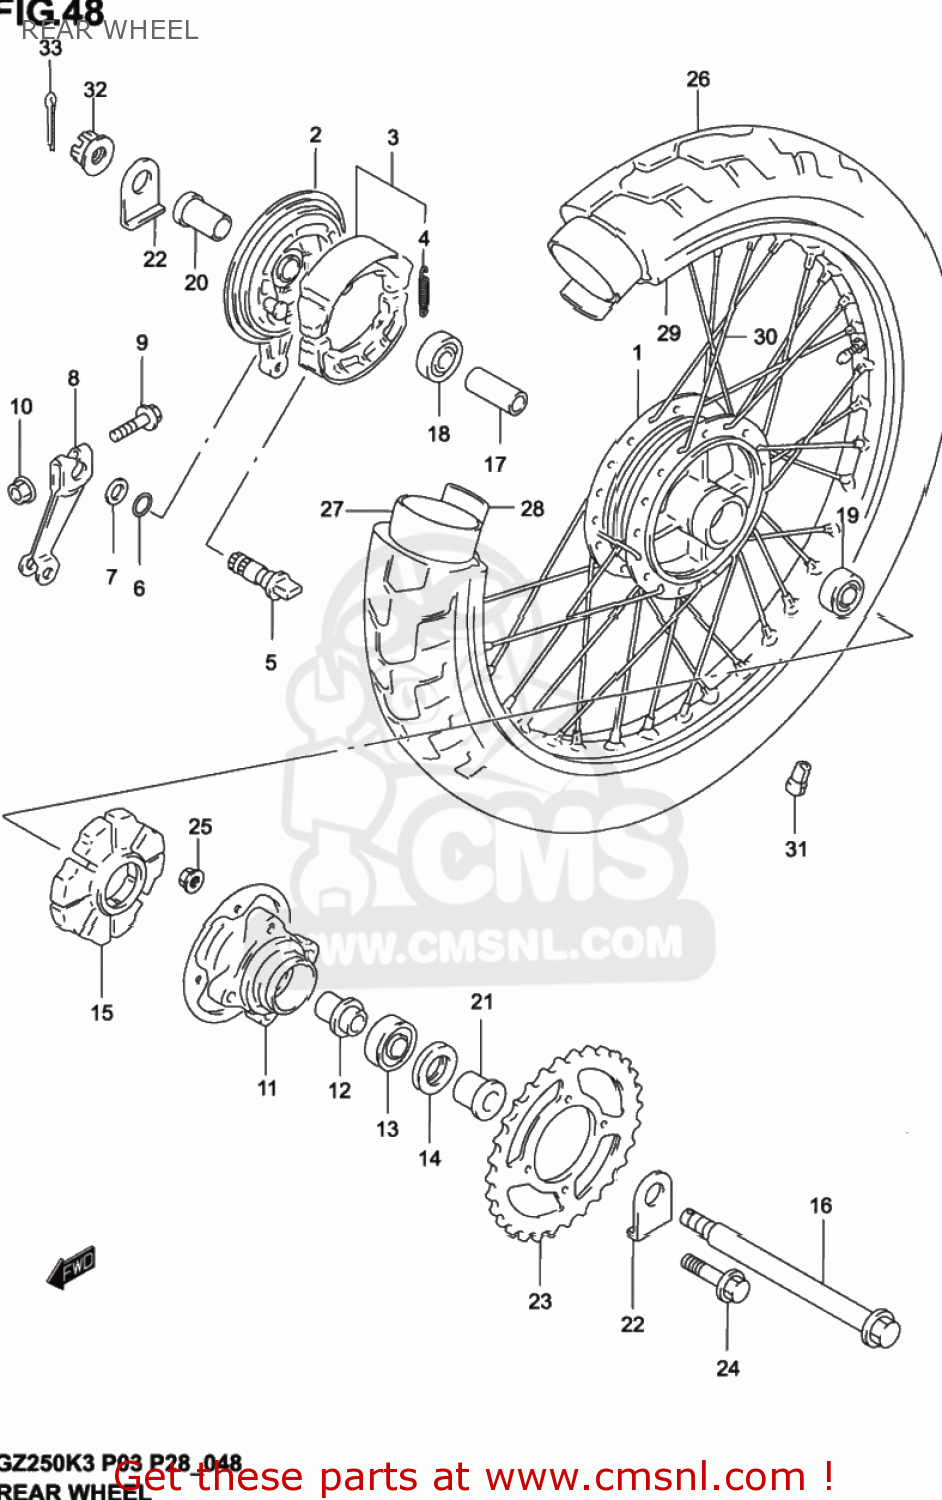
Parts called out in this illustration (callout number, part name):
1	HUB,RR WHEEL
2	PANEL,RR BRAKE ANCHOR
3	SHOE SET, BRAK
4	SPRING,RR BRAKE SHOE
5	CAM,BRAKE
6	O-RING (D:2.4 ID:13.8)
7	WASHER(14.5X22X1.6)
8	LEVER,RR BRAKE CAM
9	BOLT
10	NUT
11	DRUM,RR SPROCKET MOUNTING
12	RETAINER,RR SPROCKET DRUM
13	BEARING(20X47X14)
14	SEAL,OIL(28X47X7)
15	ABSORBER ASSY,HUB SHOCK
16	AXLE,RR
17	SPACER(15.3X21.7X63)
18	BEARING
19	BEARING, RH
20	SPACER, AXLE RH <-- 64741-12F00
21	SPACER, AXLE LH
22	WASHER,CHAIN ADJUSTER GUIDE
23	SPROCKET NICHT
24	BOLT(10X40)
25	NUT
26	TIRE,RR(130/90,
27	TUBE ASSY, WHL
28	PROTECTOR, INNER TUBE
29	RIM,RR WHEEL(15XMT3.00)
30	SPOKE SET,RR WHEEL
31	BALANCER,WHEEL (B)
32	NUT
33	PIN
